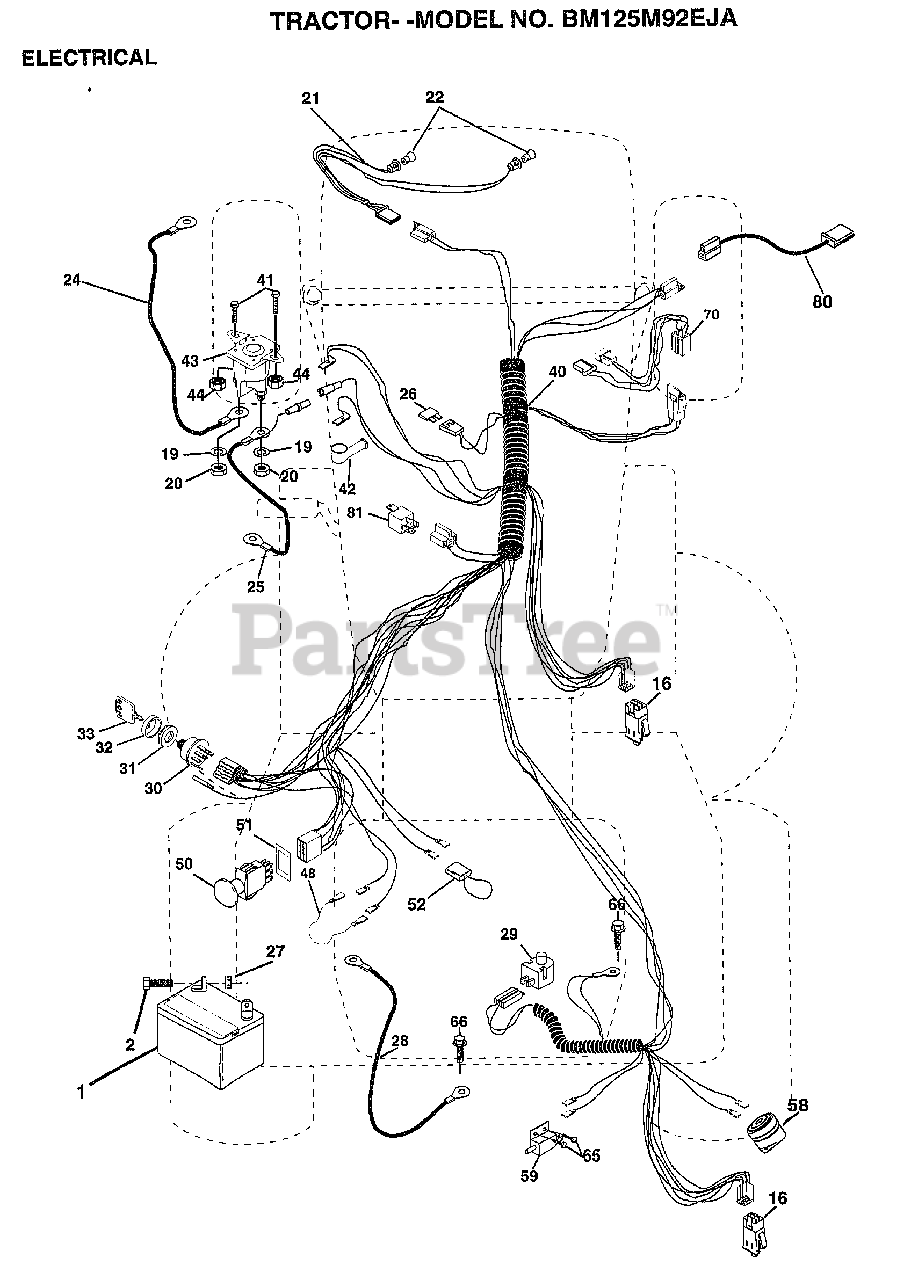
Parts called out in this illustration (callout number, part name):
2	BOLT LT
16	SWITCH INTERLOCK
20	NUT
21	HARNESS.ASM.LIGHT W/4152J
22	HEADLAMP BULB
24	"CABLE T, BATTERY"
25	CABLE.BATTERY.CRD
26	FUSE.15 AMP
27	NUT
28	"CABLE.GRD.6GA/18""BLACK"
29	SWITCH.PLUNGER
30	SWITCH IGN 4POS
31	NUT IGNITION
32	COVER KEY SWITCH
33	KEY
40	HARNESS.IGN.CRD.ELECT
41	BOLT HXHD FIN
44	NUT HXKEP 1/4X20
48	ADAPTER AMMETER
50	PTO SWITCH.BLK
51	RING RETAIN PTO
52	PROTECTION LOOP
59	SWITCH.FBI.CRD
65	SCREW
66	SCREW LT
70	HARNESS.ENGINE
80	HARNESS.CLUT.EVX.
81	RELAY ASSY T
